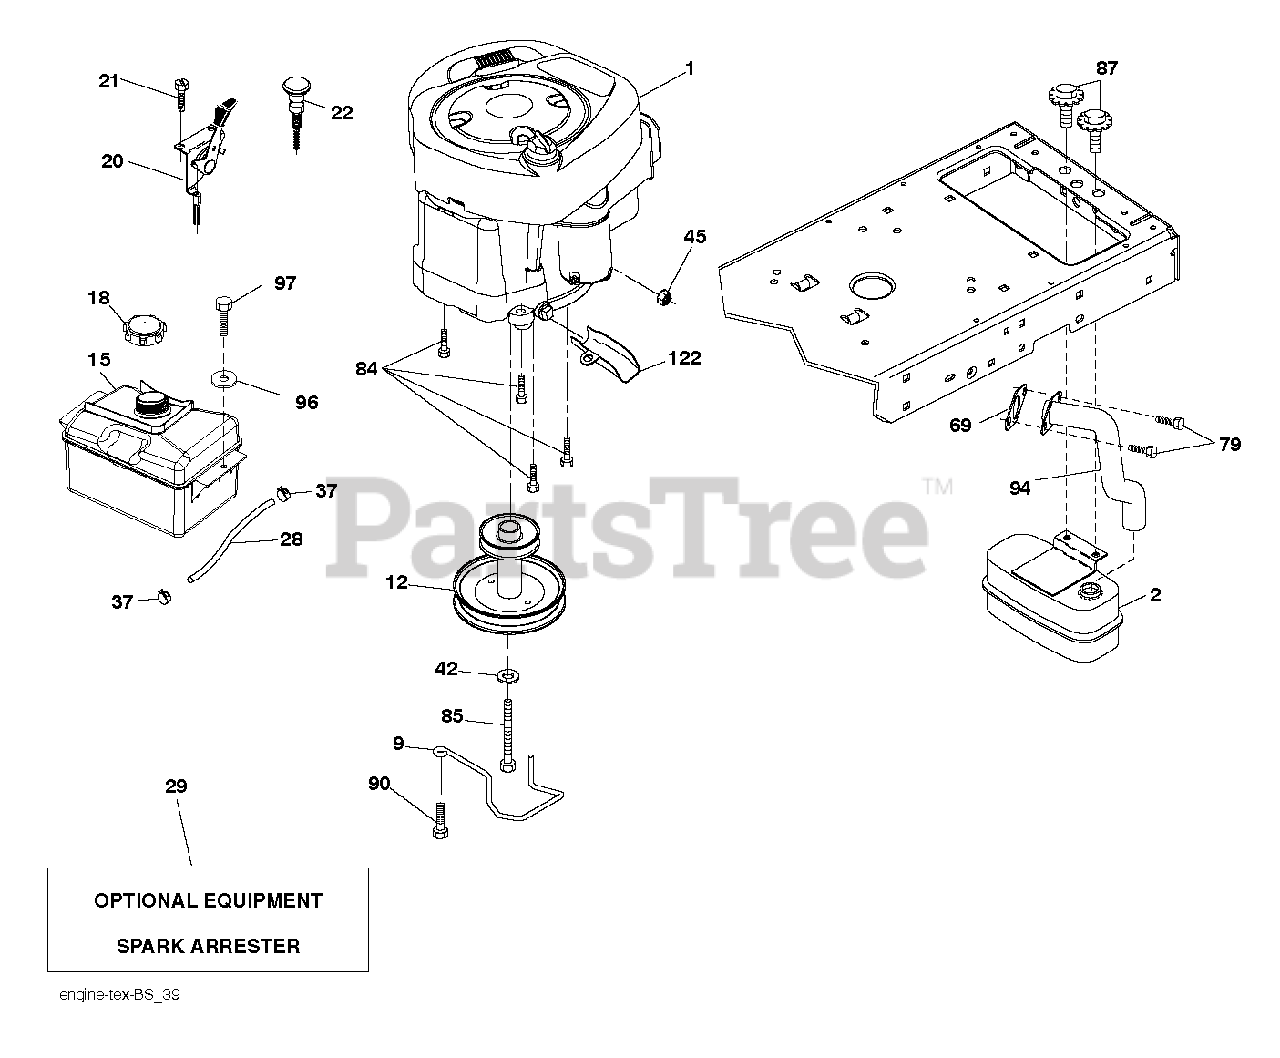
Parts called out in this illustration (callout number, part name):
2	Muffler, Single Cylinder Kohler/B&S
9	Belt Keeper, 4 25"2 Blt 431
12	PULLY ENGINE
18	CAP ASM.FUEL.2.25"FR.
20	CONTROL.TH/CK.COBRA.KO
21	SCREW.#10 X 0.750.BOS THREAD
28	LINE.FUEL.20
29	ARRESTER SPARK (OPTIONAL)
37	HOSE CLAMP
42	LOCKWASHER
45	NUT
69	REPL BY 532 27 22-93
79	SCREW.SOCKET HD.5/16-1
84	SCREW.3/8-16
85	BOLT HEX 7/16-20X4-1/4"
87	BOLT, 5/16-18 X 1 3/4
90	SCREW 3/8-16X1
94	RP.EXHAUST.TUBE.B S.2
97	SCREW HEXWSHR 1/4-20X3/4
122	EXTENSION DRAIN OIL
